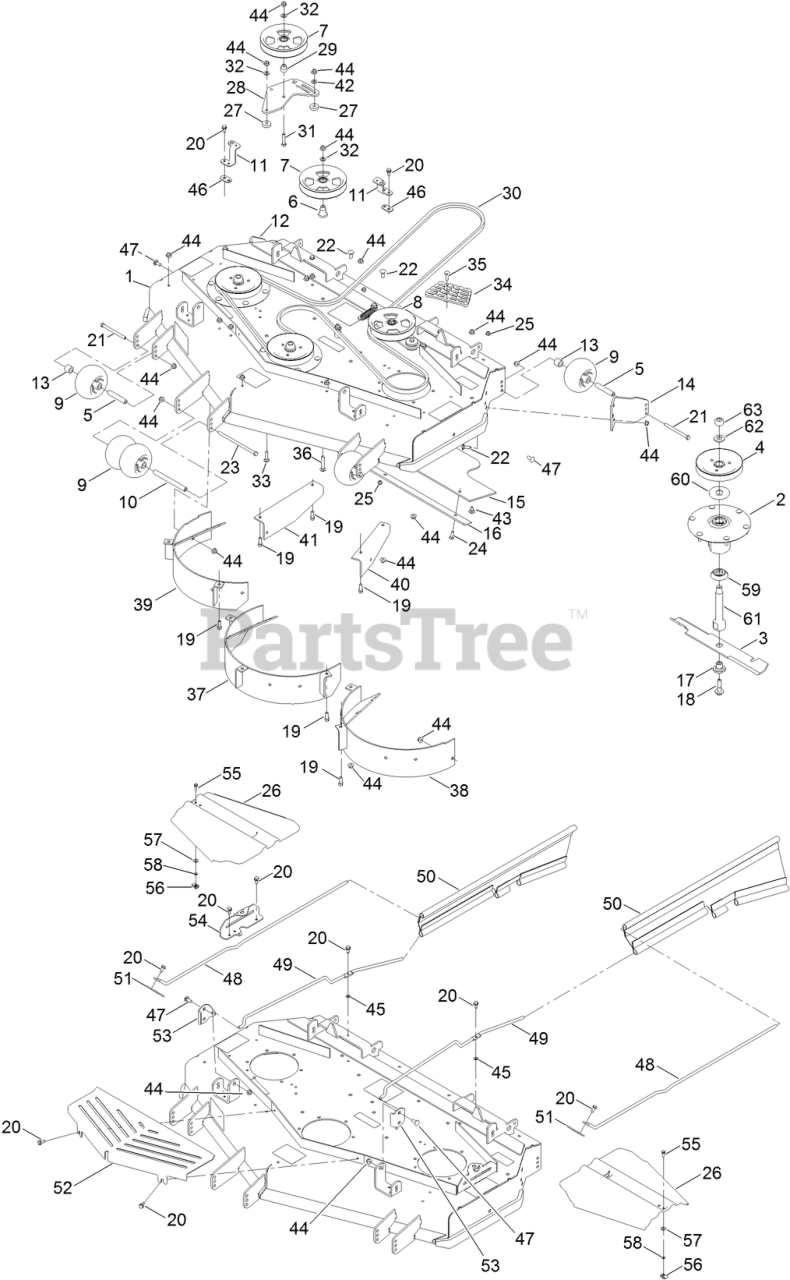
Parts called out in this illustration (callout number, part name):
1	DECK ASM
2	SPINDLE ASM
3	BLADE-FLOW, HIGH
4	SHEAVE-BLADE, DRIVE
5	TUBE-SPANNER
6	MOUNT-PULLEY
7	PULLEY-IDLER, FLAT
8	SPRING IDLER ASM
9	ROLLER-SCALP, ANTI
10	SPACER-WHEEL
11	BRACKET-COVER, TALL
12	MOUNT-ANTI SCALP, RH
13	TUBE-SPACER
14	MOUNT-ANTI SCALP, LH
15	DEFLECTOR-RUBBER
16	SKID-SKIRT
17	BUSHING-HEX
18	SCREW-SEMS
20	SCREW-HWHTF
21	SCREW-HH
22	BOLT-CARR
23	SCREW-HH
24	SCREW-CARR
25	NUT-HF, NI
26	COVER-BELT
27	SPACER
28	PLATE-IDLER
29	BUSHING-IDLER
30	BELT-V
31	SCREW-HH
32	WASHER-FLAT
33	SCREW-CARR
34	STEP-DECK
35	SCREW-CARR
36	SCREW-CARR
37	BAFFLE-CENTER
38	BAFFLE-LH
39	BAFFLE-RH
40	BAFFLE-TRAILING
41	BAFFLE-TRAILING
42	WASHER-BELLEVILLE
43	SCREW-CARR
44	NUT-HF, NI
45	NUT-PUSH
46	SPACER-BELT COVER
47	SCREW-CARR
48	ROD-SUPPORT, UPPER
49	ROD SUPPORT, LOWER
50	GUARD SIDE
51	BRACKET-MOUNTING, UPPER ROD
52	SHIELD-FRONT
53	BRACKET-MOUNTING, FRONT
54	BRACKET-SUPPORT, SPINDLE COVER
55	SCREW-HWH
57	WASHER-THRUST
58	PUSHNUT-RETAINER, BOLT
59	GUARD-BOTTOM
60	GUARD-BEARING, TOP
61	SHAFT-SPINDLE
62	WASHER
63	NUT-HEX
